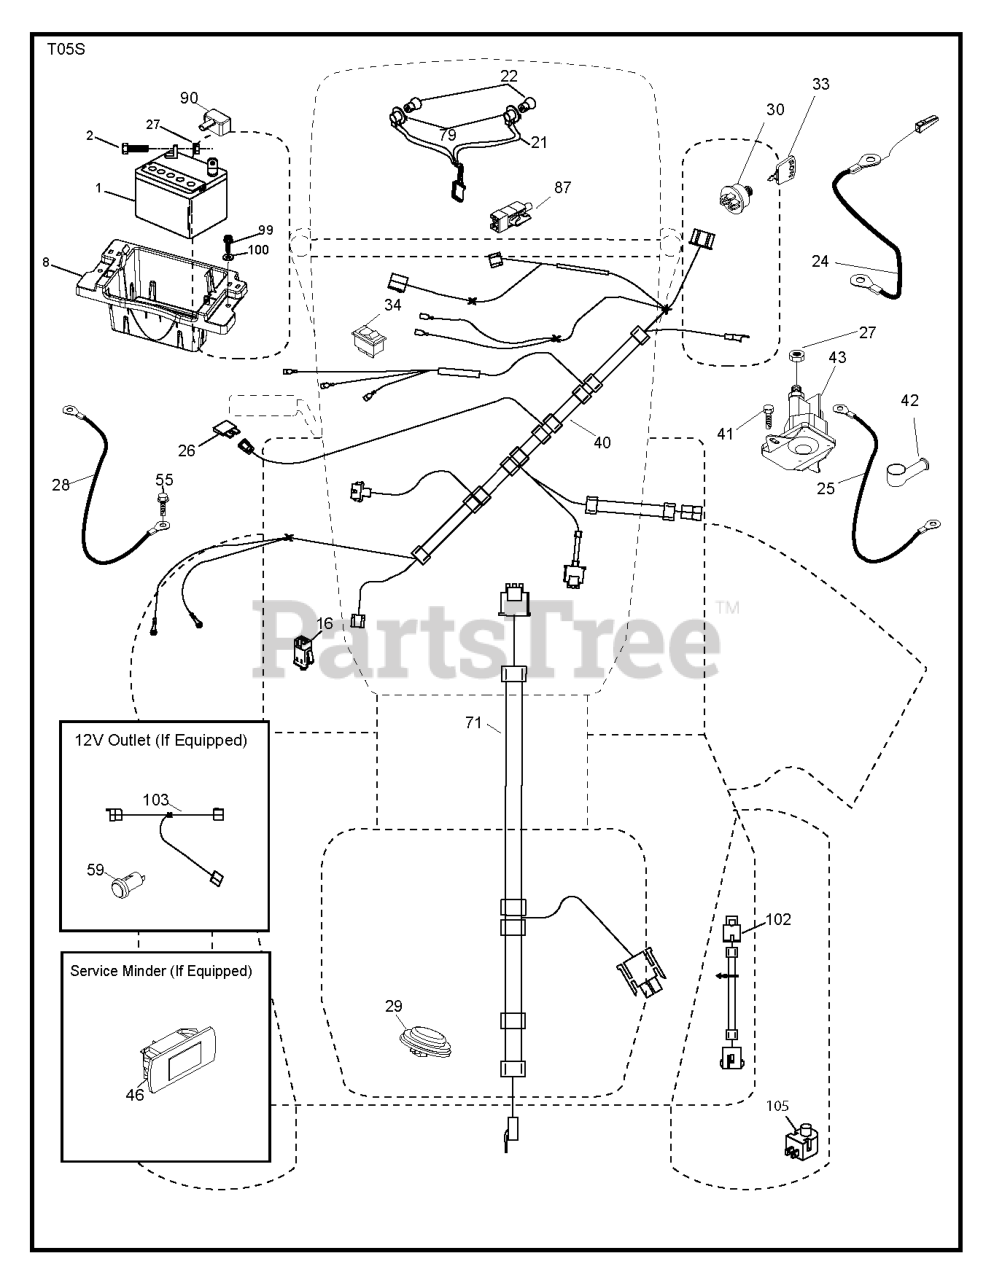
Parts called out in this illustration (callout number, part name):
1	Battery 12 Volt 25 Amp
2	BOLT.HEX.1/4.X.3/4.DICHROMATE
8	TRAY.ASM.BATTERY.FRT.TEX.CARB
16	SWITCH INTERLOOK PUSH-IN
21	HARNESS.LIGHT W/4152J BULBS
24	CABLE.FRBATT.W/WIRE.8GA.8
25	CABLE.STARTER.8GA.17.5
26	FUSE 20AMP
27	NUT
28	CABLE.GROUND.21"BLK.8GA.90T
29	SWITCH.SEAT.DELTA.OPC.
30	SWITCH.IGN.DELTA.W.LGH.ROS
33	KEY.CHAIN.BLISTER.PACK.GEN.USA
40	HARNESS.IGN.DASH.CBL.YTGT.PRED
41	SCREW
42	TERMINAL COVER
43	SOLENOID.STARTER.BRASS.PLUNGER
46	GUAGE.SRVCMNDR.HRMTR.
55	SCREW 5/16"
71	HARNESS-CHASSIS SUB
79	BULB HOLDER ASM.
87	SWITCH.INTRLCK.CLUTCH.
90	COVER.TERMINAL.BATTERY
99	SCREW HEXWSHR 1/4-20X3/4
102	HARNESS PIGTAIL PCH TEX ROS
105	REVERSE SWITCH
